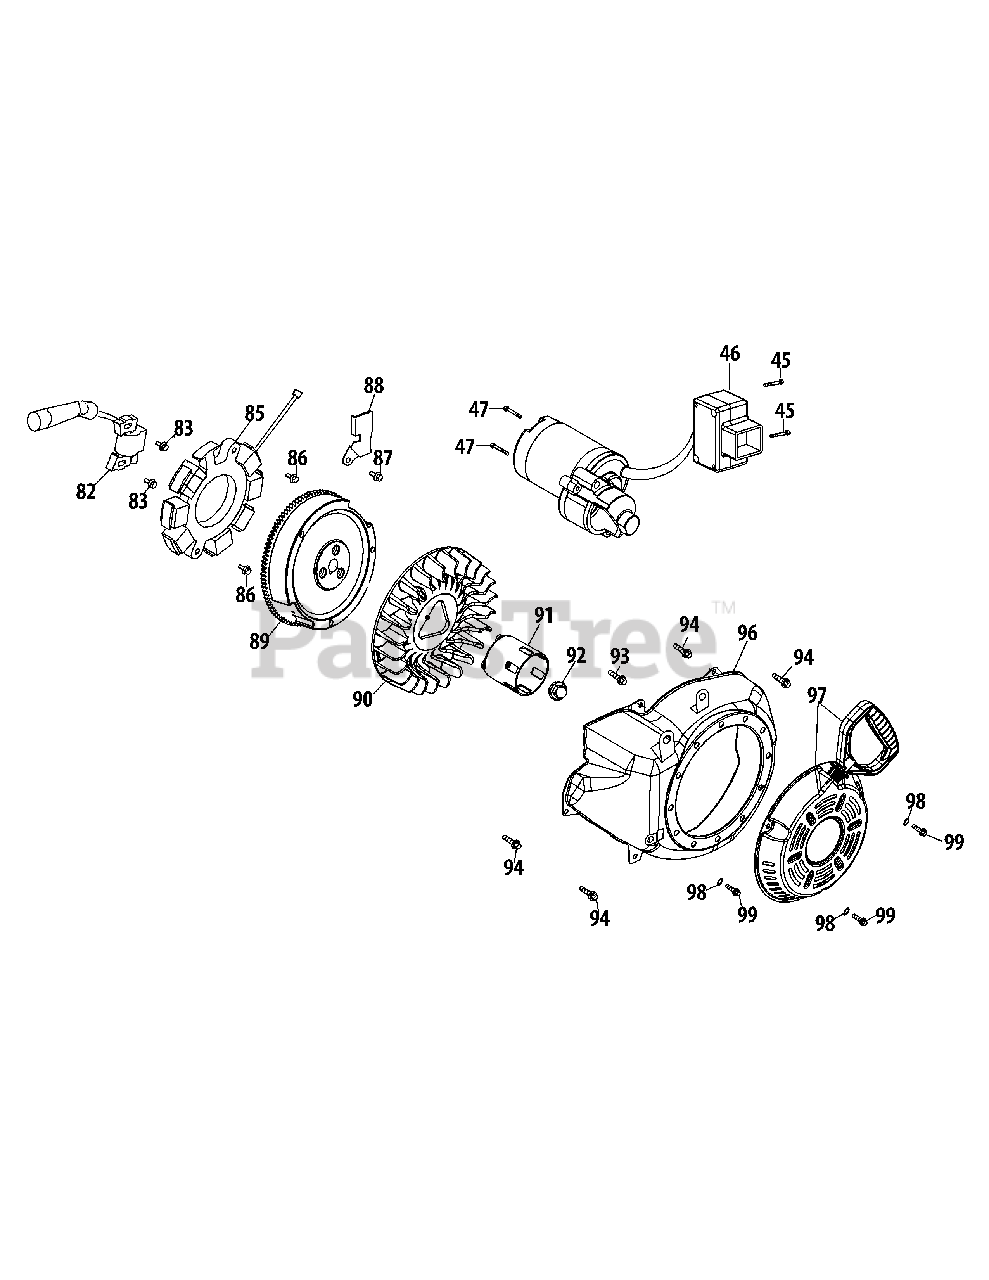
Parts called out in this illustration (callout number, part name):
45	Bolt M4×55
46	Electric Starter
47	Bolt M8×55
82	Ignition Coil Assembly
83	Ignition Coil Bolt
85	Alternator Assembly
86	Bolt M6×30
87	Bolt M6×8
88	Wire Plate
90	Cooling Fan
91	Starter Cup
92	Nut, Special, M16×1.5
93	Bolt M6×16
94	Bolt M6×12
96	Blower Housing
97	Recoil Starter
98	Gasket 6
99	Bolt M6×10
